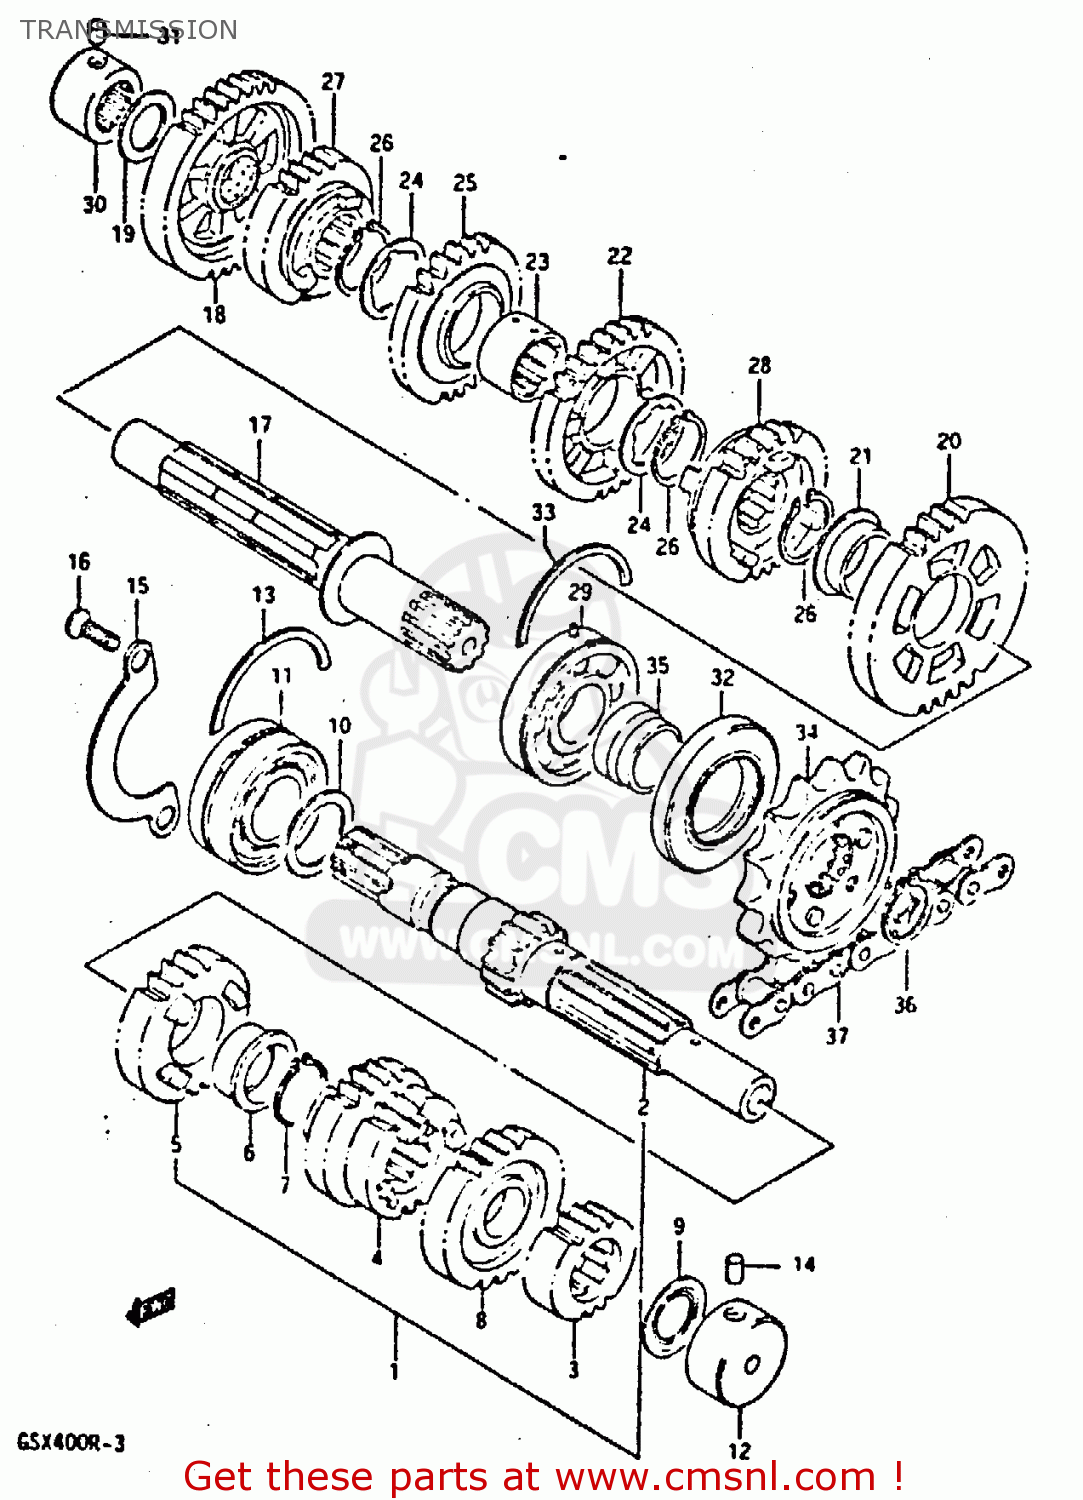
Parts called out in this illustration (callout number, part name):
1	SHAFT,COUNTER
2	SHAFT,COUNTER
3	GEAR,2ND DRIVE
4	GEAR.3RD DRIVEN
5	3RD/4TH DR GR 1
6	BUSH
7	CIRCLIP
8	3RD/4TH DR GR 1
9	SEAL,OIL(17X28.5X2.5)
10	WASHER
11	BEARING(25X52X19.6)
12	BEARING
13	C RING
14	PIN
15	RETAINER,CNTR SHAFT BEARING
16	SCREW
17	AANDRIJFAS
18	GEAR,FIRST DRIVEN
19	WASHER,THRUST
20	GEAR,2ND DRIVEN
21	BUSH
22	GEAR,3RD DRIVEN
23	SPACER,3RD DRIVEN GEAR
24	WASHER,LOCK
25	GEAR,FOURTH DRIVEN
26	RING,SNAP
27	GEAR,5TH DRIVEN(NT:30)
28	GEAR,SIXTH DRIVEN
29	BEARING
30	BEARING(20X34X20)
31	PIN
32	SEAL,OIL(30X56X6)
33	C RING
34	ENGINE SPROCKET (14T)
35	BUS
36	CIRCLIP
37	KETTING
